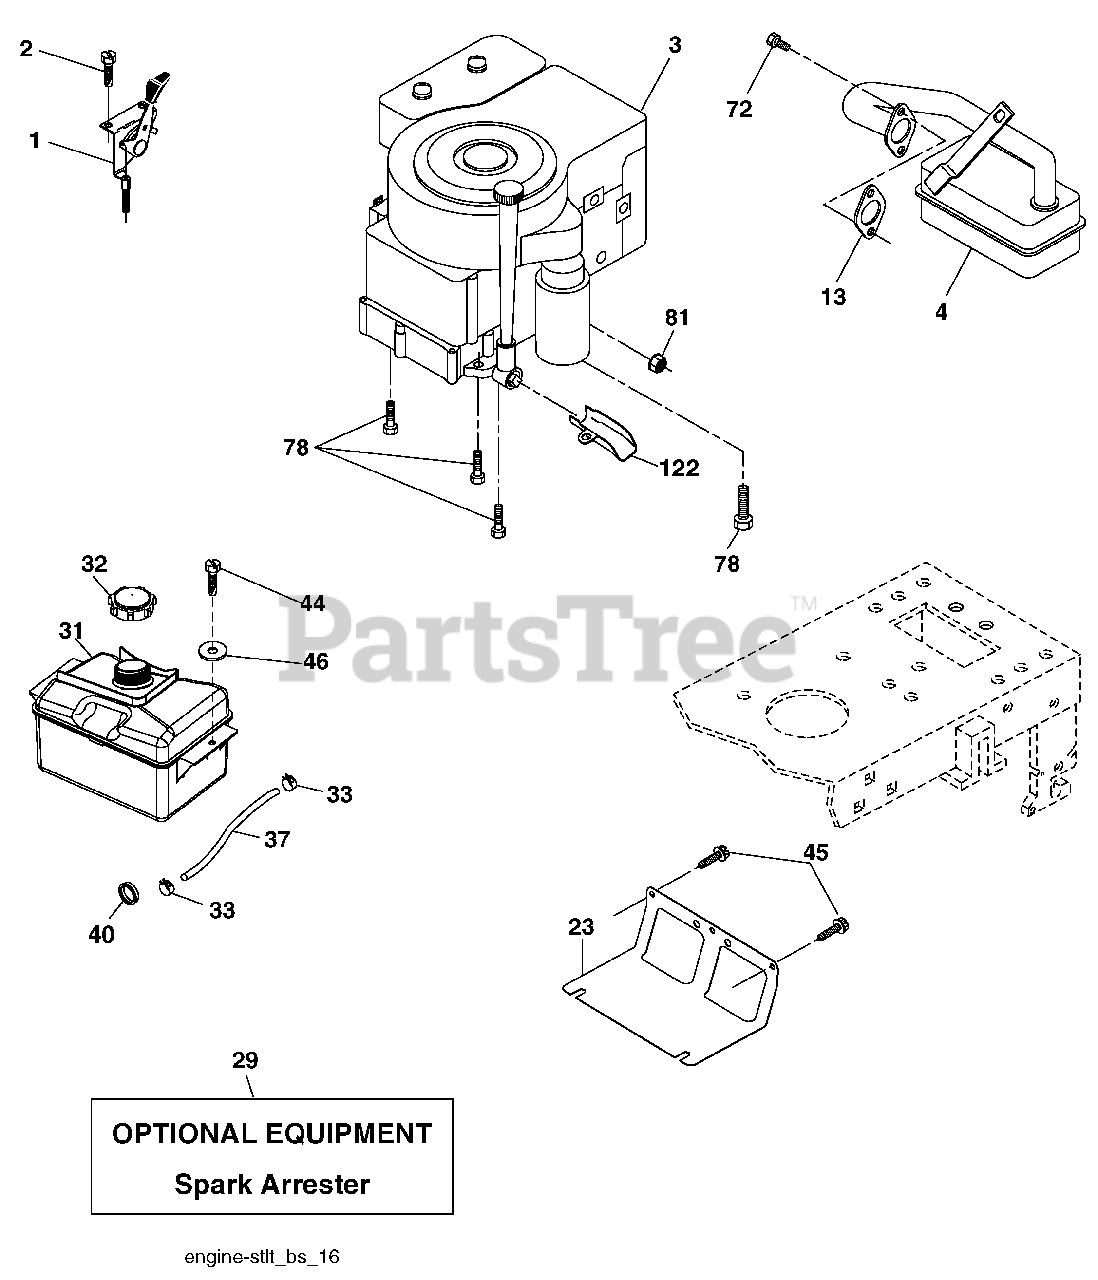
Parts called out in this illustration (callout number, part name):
1	Control Th/ch Flag
2	Screw Hex Thd Cut 1/4-20 x 1/2
4	Muffler Exhaust B&S
13	Gasket Eng 1 313 Id Tin Plated
23	Shield BRN/DBR Guard
29	Kit Spark Arrestor (Flat Scrn)
31	Tank Fuel Front
32	Cap Fuel
33	Clamp Hose
37	Line Fuel
40	Bushing Snap Nyl Blk Fuel Line
44	Screw Thdrol 1/4-20 x 3/4
45	Screw Hex Wsh Thdrol 3/8-16
46	Washer 9/32 x 7/8 x 16 Ga.
72	Screw Socket Head 5/16-18 x 3/4
78	Screw 3/8-16 x 1-1/4
81	Nut Keps Hex 1/4-20 unc
122	Extension Drain Oil
